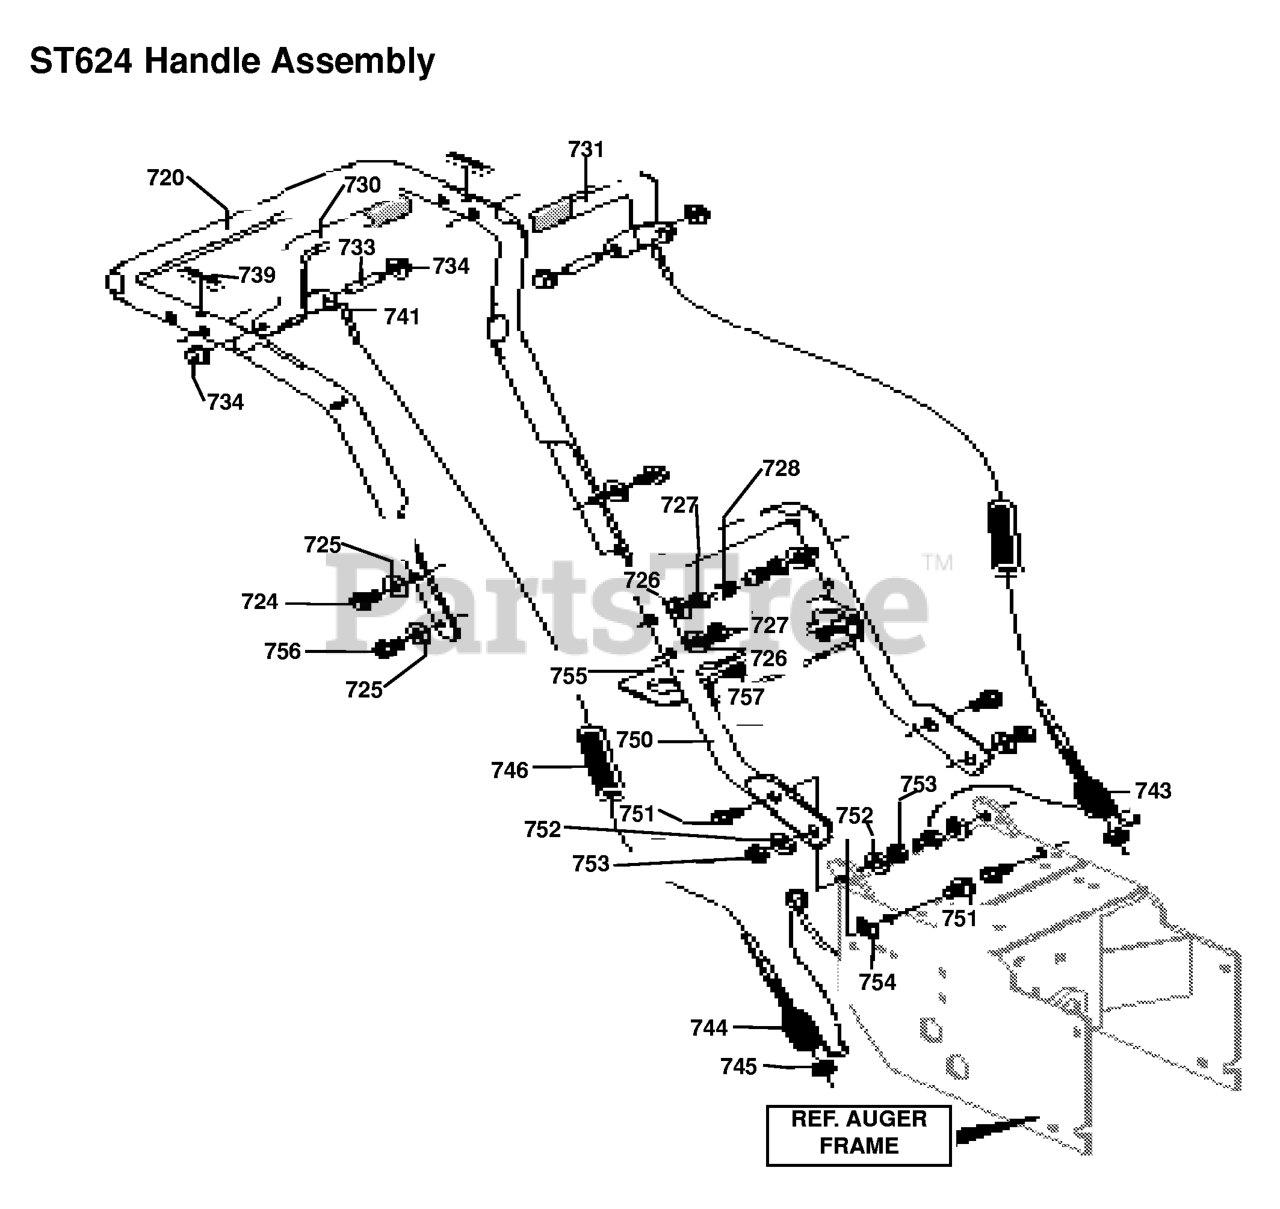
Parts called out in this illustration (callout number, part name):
720	HANDLE, UPPER
725	WASHER, FLAT .344X .69X.
726	WASHER, HVSPTLK .328X.60X
727	NUT, 5/16-18 REGHEX
728	STOP, RED PLASTIC
730	Kit for Handle, Assy RH
731	Kit for Handle, Assy RH
733	CLUTCH PIN
734	NUT, PUSH ON CAP .312 OD
741	CABLE, CLUTCH
743	SPRING TENSION
744	CLUTCH SPRING
746	BOOT, CLUTCH SPRING
750	LOWER HANDLE
751	SCREW, 5/16-18X1.00 HHC
752	WASHER, HVSPTLK .328X.60X
753	NUT, 5/16-18 REGHEX
754	PUSHNUT, 5/16 BOLT RETAIN
755	BRACKET,GEAR SELECTOR
756	SCREW-5/16-18 X .75
757	SCREW, .25X.75X.75HHWAPLA
